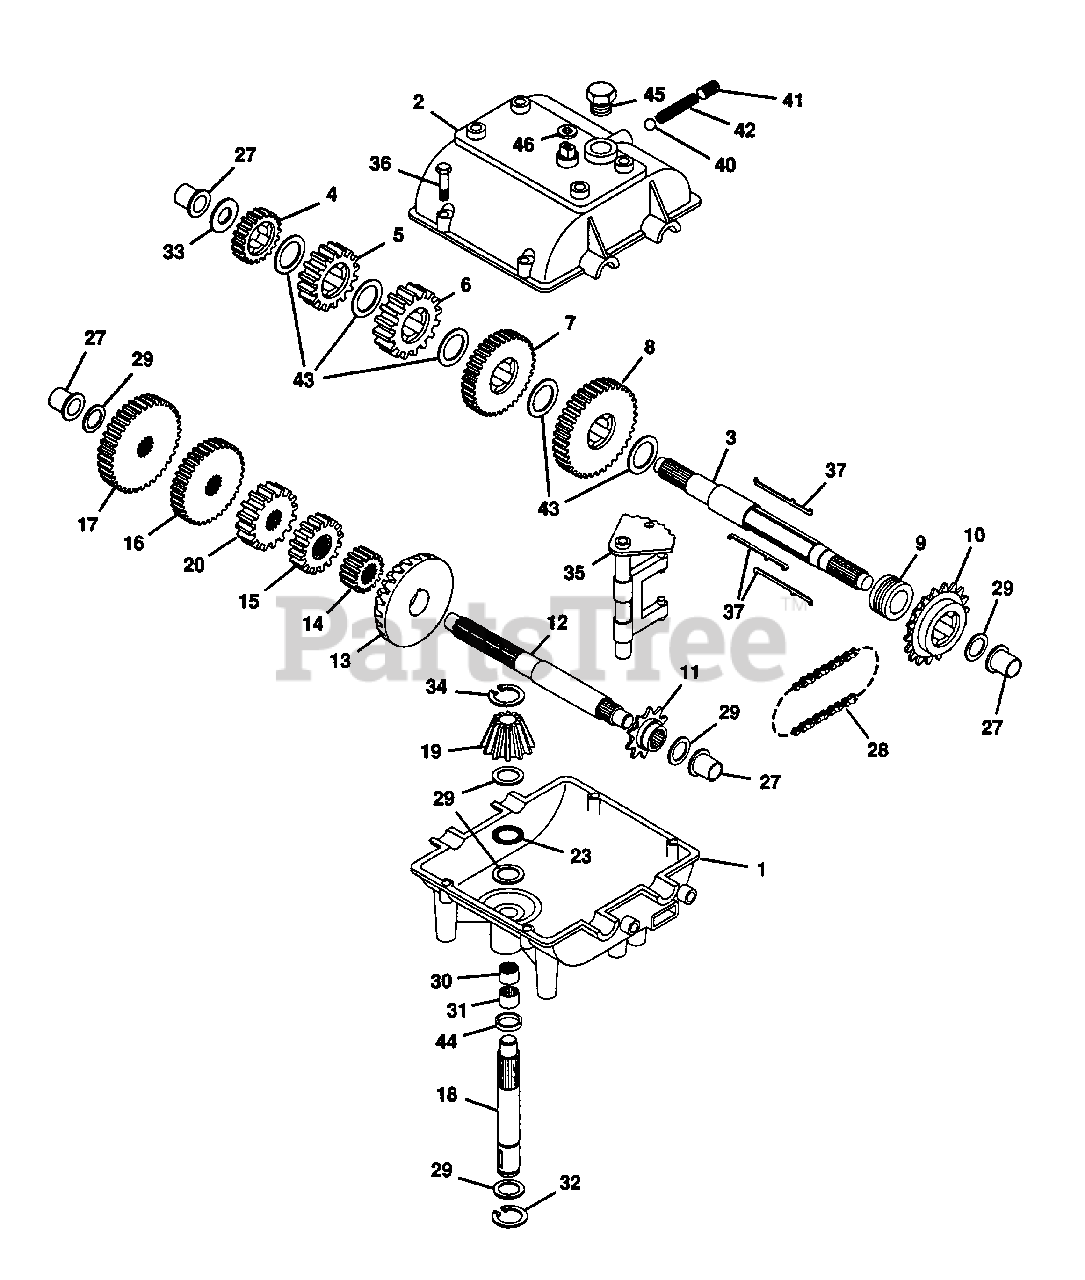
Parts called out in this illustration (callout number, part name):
1	CASE, TRANSMISSION
2	COVER, TRANSMISSION
3	SHAFT, OUTPUT & BRAKE
4	GEAR, SPUR (27 TEETH)
5	GEAR, SPUR (30 TEETH)
6	GEAR, SPUR (32 TEETH)
7	GEAR, SPUR (35 TEETH)
8	GEAR, SPUR (37 TEETH)
9	COLLAR, SHIFT
10	SPROCKET (18 TEETH)
11	SPROCKET (9 TEETH)
12	SHAFT, COUNTER
13	GEAR, BEVEL (42 TEETH)
14	GEAR, SPUR (12 TEETH)
15	GEAR, SPUR (15 TEETH)
16	GEAR, SPUR (20 TEETH)
17	GEAR, SPUR (23 TEETH)
18	SHAFT, INPUT
19	BEVEL PINION, INPUT
20	GEAR, SPUR (18 TEETH)
23	BEARING, THRUST
27	BUSHING, FLANGED
28	CHAIN, ROLLER (NO. 41 CHAIN, 24 LINKS)
29	WASHER, THRUST
30	BEARING, NEEDLE
31	BEARING, NEEDLE
32	RING, RETAINING
33	WASHER, THRUST
34	RING, RETAINING
35	ROD & FORK ASSEMBLY, SHIFT
36	SCREW, HHD TAPTITE, 1/4-20X1.25
40	BALL, STEEL 5/16
41	SCREW, SET 3/8-16X3/8
43	WASHER, THRUST
45	PLUG, THREADED
46	SEAL, SQUARE CUT
